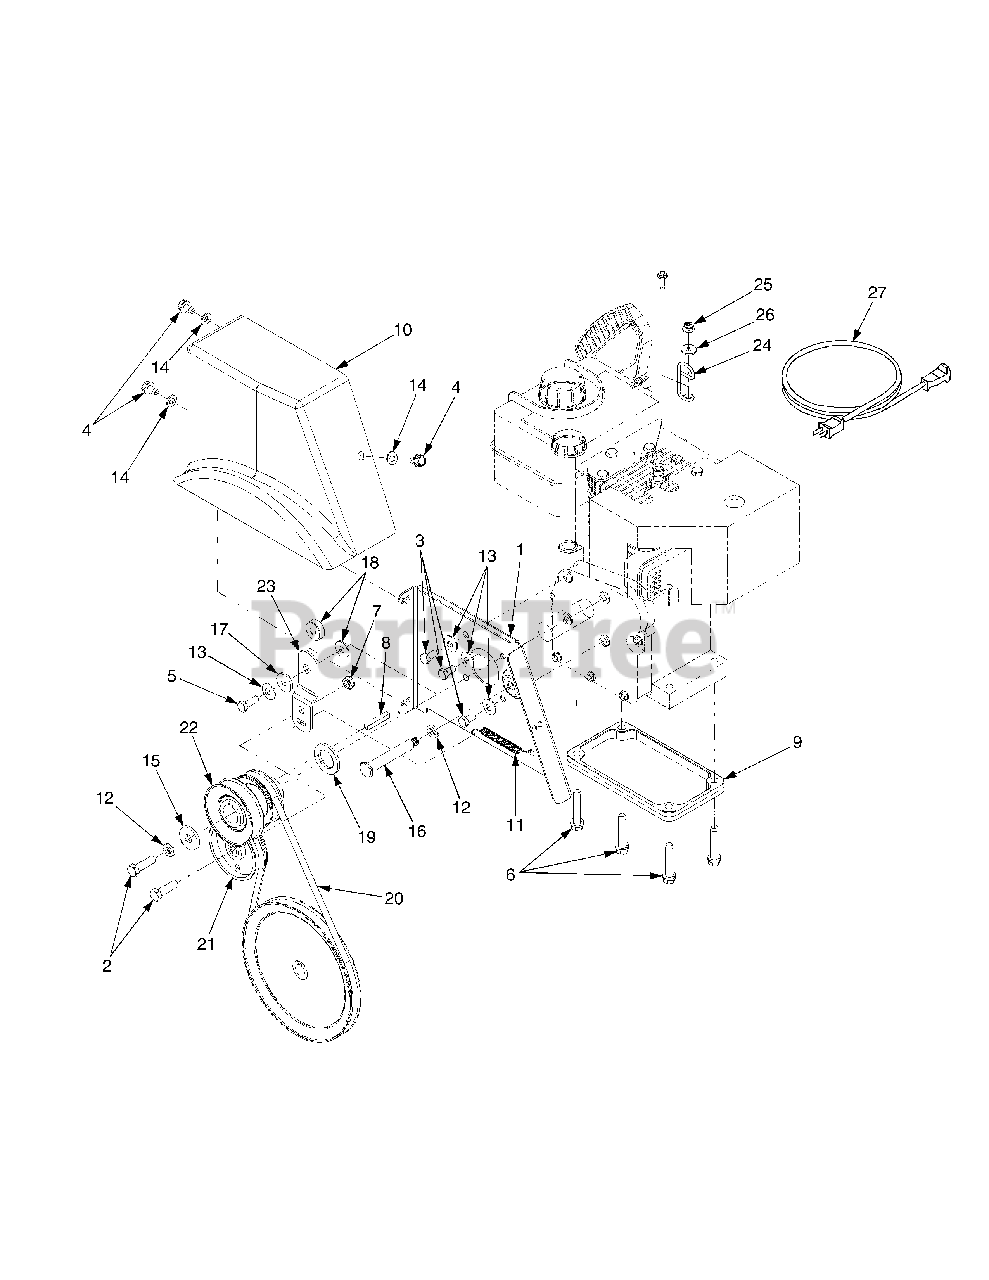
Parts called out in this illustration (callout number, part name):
3	Screw, Hx Cap, 5/16-24 x .625 GR5
4	Screw, Hx Wash Hd Tapp, 5/16-18 x .5
5	Screw, Hx Cap 28" S.T. Only, 5/16-24 x 1.25 GR5
5	Screw, Hx Cap 33" and 45" S.T. Only, 5/16-24 x .875 GR8
6	Screw, Hx Sems Tapp 28" S.T.Only, 3/8-16 x 1.875
6	Screw, Hx Sems Tapp 33" and 45" S.T. Only, 3/8-16 x 1.25
7	Nut, Hx Insert Jam Lk, 3/8-24 GR5
8	Key, Square, 1/4 x 1.5
9	Spacer, .56, 28" S.T. Only
10	Cover, Belt
11	Spring, Extension
12	Washer, Lock
13	Washer, Belleville, .34 x .872 x .06
14	Washer, Flat, .33 x .63 x .0635 ...
15	Washer, Flat, Hdn .45 x 1.25 x .164
16	Screw, Shoulder 28" S.T. Only, .498 x 3.245:3/8-16
16	Screw, Shoulder 33" and 45" S.T. Only .498 x 2.99:3/8-16
17	Spacer, Shoulder
18	Spacer 28" S.T. Only, .331 x 1.01 x .36
18	Washer, Flat, 33" and 45" S.T.,Only, .349 x .879 x .063
19	Spacer, 28" S.T. Only, 1.02 x 1.63 x .1425
20	V-Belt, 3/8 x 35.5
21	Pulley, Flat Idler, 3.0 OD
22	Pulley, Double, 3.25 OD: 2.75 OD
23	Bracket, Idler
24	Guide, Chute Cable
25	Nut, Hx Flnge Insert Lk 33" and 45" S.T. Only, 1/4-20 GrF
26	Washer, Flat 33" and 45" S.T.Only — .28 x .74 x .063
27	Extension Cord, 110V, 3-prong ...
